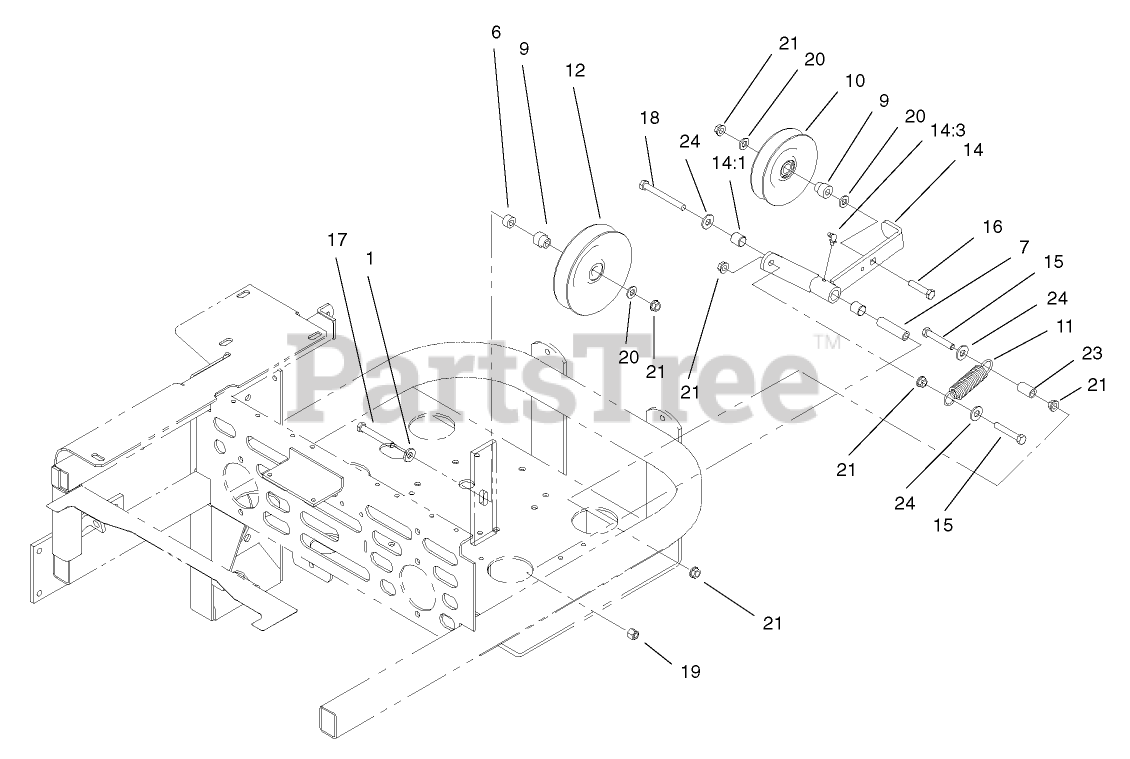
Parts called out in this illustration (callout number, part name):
1	WASHER-BELLEVILLE
6	SPACER
7	BUSHING-PIVOT, IDLER
9	BUSHING-IDLER
10	Idler
11	SPRING-EXTENSION
12	PULLEY-IDLER
14	IDLER ARM ASM
14:1	SLEEVE-BEARING
14:3	FITTING-GREASE, 90 DEG
15	SCREW-HH
16	SCREW-HH
17	SCREW-HH
18	SCREW-HH
19	NUT-LOCK, NI
20	WASHER-FLAT
21	NUT-HHF, WHIZ
23	SPACER
24	WASHER-FLAT
